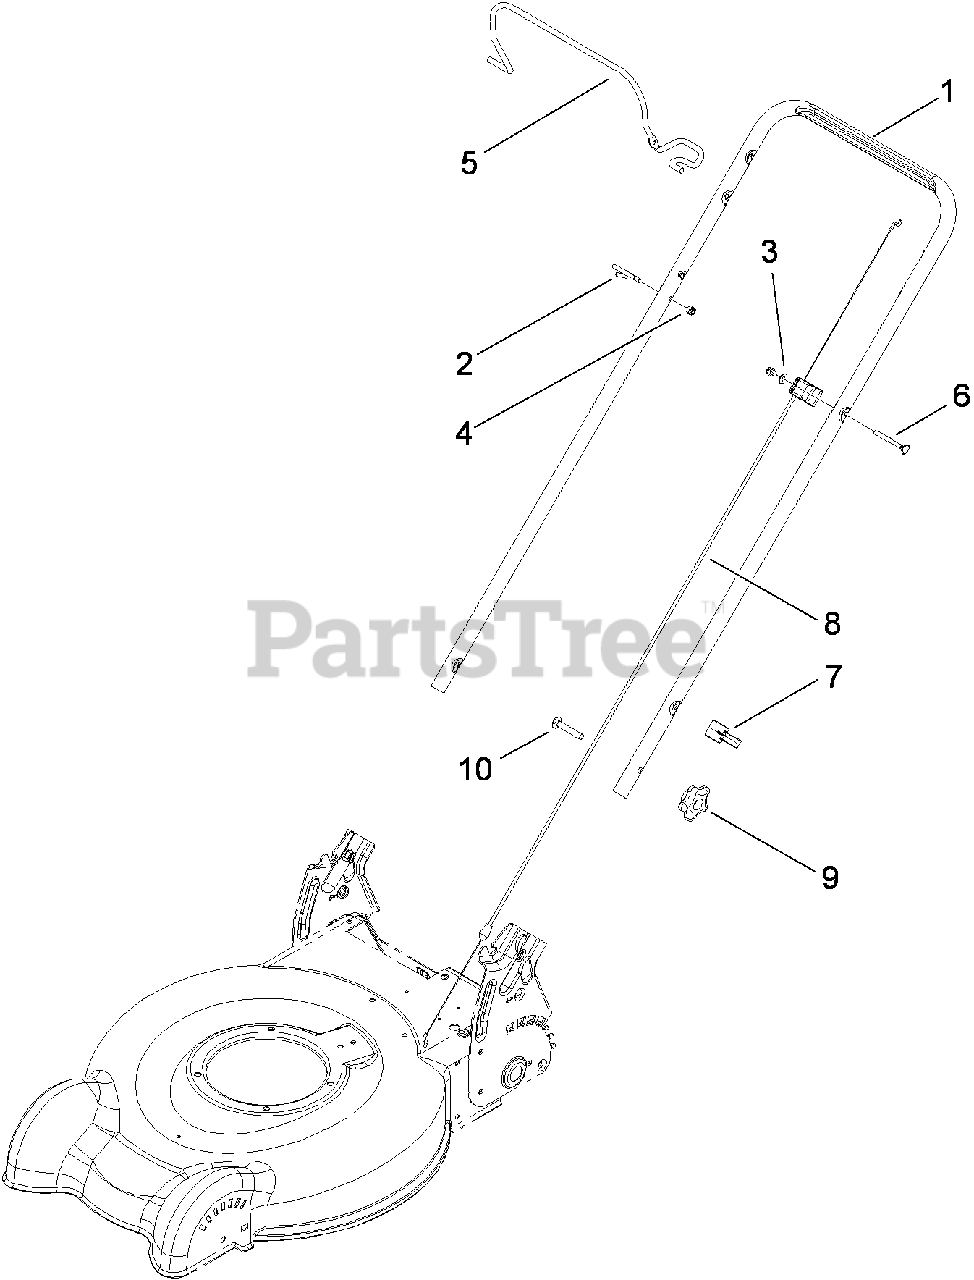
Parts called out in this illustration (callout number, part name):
1	HANDLE
2	GUIDE-ROPE
3	WASHER-FLAT
4	NUT-LOCK, NI
5	BAIL-BRAKE, 2-BAIL FLAT
6	SCREW-HANDLE
7	Guide-Cable
8	CABLE-BRAKE
9	KNOB-LOCKING
10	Screw-CARR
